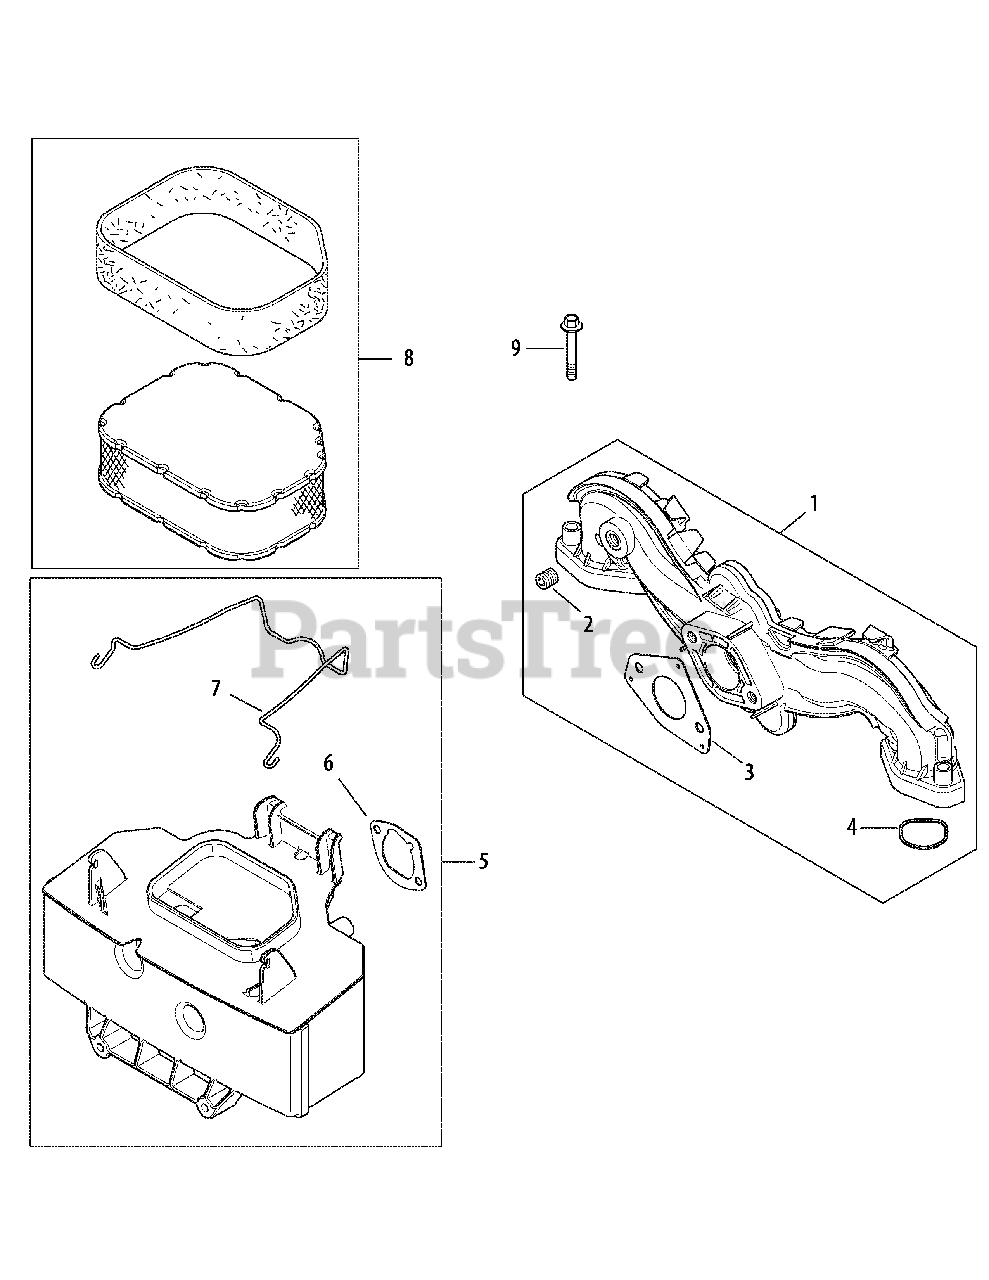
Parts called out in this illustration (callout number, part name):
1	Intake Manifold Kit (Inc. 2-4)
2	Carburetor Gasket
3	Intake Port O-Ring
4	Ctsk. Pipe Plug, 1/8
5	Air Cleaner Base Kit (Inc. 5 & 6)
6	Air Cleaner Base Gasket
7	Air Cleaner Element Latch
8	Air Filter Element / Pre-Cleaner
9	Flg. Screw, M6 X 1.0 X 40
